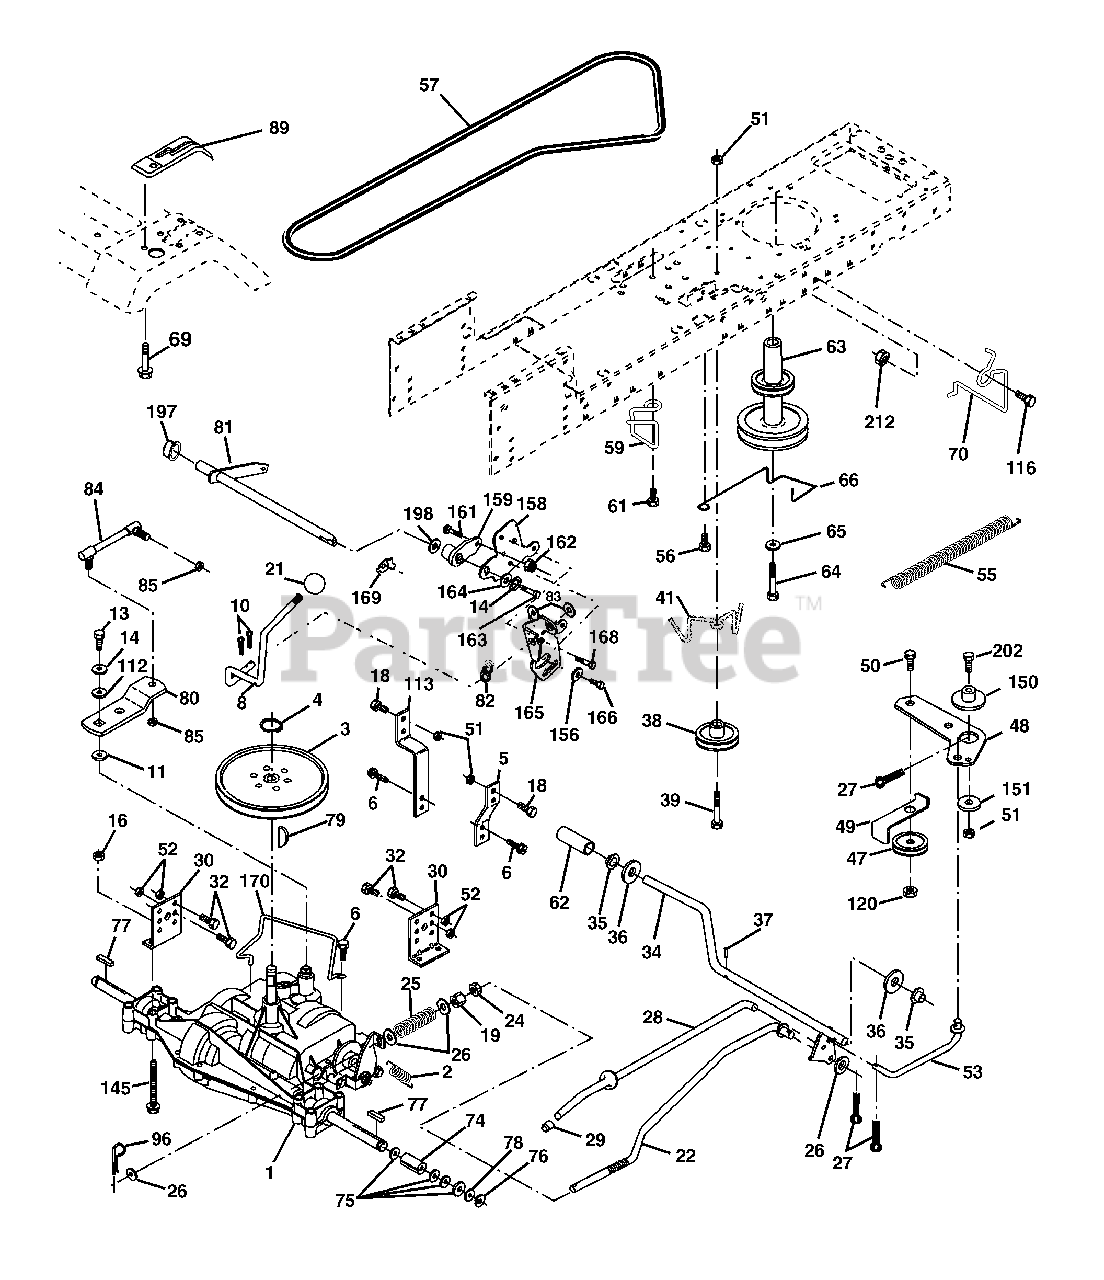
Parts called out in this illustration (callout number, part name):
2	Spring Return Brake T/a Zinc
3	Pulley Transaxle 18" tires
4	Ring Retainer # 5100-62
5	Strap Torque 30 Degrees
6	Screw 5/16-18 X 3/4
8	Rod Shift Fender Adjust Lt
10	Pin Cotter 1/8 X 1 Cad
11	Washer Plate Shf 388 Sq Hole
13	Bolt 1/4-28 Unf Gr 8 W/Patch
14	Washer Lock Hvy Helical
16	Nut Lock Hex w/ins 5/16-18
18	Bolt, Fin Hex 3/8-16 UNC x 1 Gr. 5
19	Nut Lock 3/8-16 Unc
21	Knob
22	Rod Brake Blk Zinc 26 840
24	Nut Hex Jam 3/8-16 Unc
25	Spring Rod Brake 2 00 Zinc
26	Washer 13/32 X 13/16 X 16 Ga
27	Pin Cotter 1/8 X 3/4 Cad
28	Rod Brake Parking LT/YT
29	Cap Brake Parking
30	Bracket Mtg Transaxle
32	Bolt Hex Hd 5/16-18unc X 3/4
34	Shaft Asm Pedal Foot
35	Bearing Nylon Blk 629 Id
36	Washer 21/32 X 1 X 16 Ga
37	Pin Roll 3/16 X 1"
38	Pulley Composite Flat
39	Bolt Fin Hex 3/8-16 unc X 3
41	Keeper Belt Flat Idler
47	Pulley Idler V Groove Plastic
48	Bellcrank Asm
49	Retainer Belt Style Spring
50	Bolt Carr Sh 3/8-16 x 1-1/2 Gr. 5
51	Nut Crownlock 3/8-16 Unc
52	Nut Crownlock 5/16-18 Unc
53	Link Clutch
55	Spring Return Clutch 6 75
56	Screw 3/8-16 x 1-1/4
57	V-Belt Ground Drive 95 25
59	Keeper Belt Span Ctr
61	Screw 3/8-16 x .875
62	Cover Pedal Blk Round
63	Engine Pulley
64	Bolt Hex
65	Washer Lock Hvy Hlcl Spr 7/16
66	Keeper Belt Engine Foolproof
69	Screw Hex wsh Hi Lo 1/4 x 1/2 unc
70	Guide Belt Mower Drive RH
74	Spacer Axle
75	Washer 25/32 X 1 1/4 X 16 Ga
76	E-ring #5133-75
77	Key Square 2 0 X 1845/ 1865
78	Washer 25/32 X 1-5/8 X 16 Ga
79	Key Woodruff #9 3/16 x 3/4
80	Arm Shift
81	Shaft Asm Cross Tapered
82	Spring Torsion T/a
83	Washer 17/32 X 3/4 X 16 Ga
84	Link Transaxle PMST/18" Zinc
85	Nut Lock Center 1/4 - 28 FNTHD
89	Console Shift STLT
96	Retainer Spring 1"
112	Washer 9/32 x 3/4 x 10 Ga.
113	Strap Torque LT
116	Bolt Rdhd Sq Neck 3/8-16 x 1
120	Nut Lock Flg. 3/8-16 Unc
145	Bolt Hex FLGHD 5/16-18 Gr. 5
150	Spacer Retainer
151	Washer 13/32 x 2 x 10
156	Washer Srrted 5/16ID x 1.125
158	Bracket Shift Mount
159	Hub Shift
161	Bolt Rdhd Sqnk 1/4-20 x 3/4 Gr
162	Nut Crownlock 1/4-20 Unc
163	Bolt Hex Fin 1/4-20 Unc x 1 Gr 5
164	Washer 5/8 x .281 x 10 Ga
165	Bracket Pivot Lever
166	Screw 5/16-18 x 5/8
168	Bolt Shoulder 5/16-18 x .561
169	Plate Fastening
170	Keeper Belt Transaxle Gear
197	Nyliner Snap-In
198	Washer Nyliner
202	Bolt 3/8-16 x 1-3/4 Gr. 5
212	Nut Hexflange Lock
